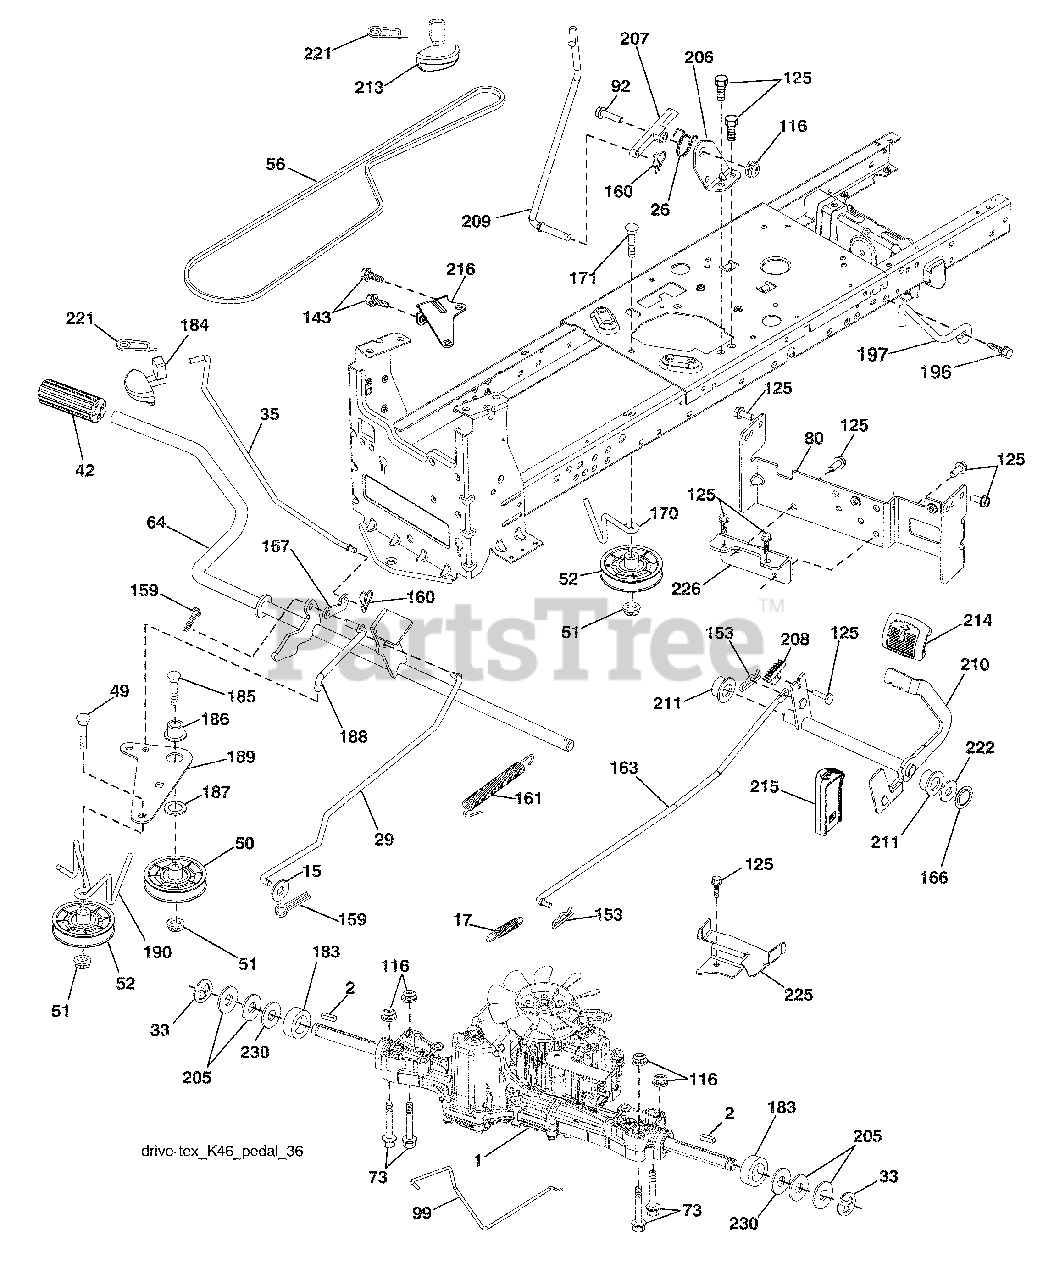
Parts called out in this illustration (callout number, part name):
1	Transaxle, TUFFTORQ K46 BT
15	Washer 13/32 x 13/16 x 16 Ga.
17	Spring, Brake
26	Spring Return Cruise
29	Rod, Brake
35	Rod, Brake, Park
42	Cover, Foot Pedal
50	Pulley Idler Flat
51	Lock Nut 3/8-16
52	Idler V-Groove 910" Offset
56	V-Belt, Drive
64	Shaft Asm. Pedal Brake Control
73	Bolt Hex Flghd 5/16-18 Gr. 5
80	Bracket Strap Torque
92	Bolt Fin Hex 5/16-18 unc x 1.25
99	Rod Asm Bypass
116	Nut Lock Hex Flange 5/16-18
125	Screw 5/16-18 x 3/4
143	Screw 5/16-18 x 1/2
153	Retainer Spring
159	Pin Cotter 1/8 x 3/4
160	Retainer Clip
161	Spring, Return, Clutch
163	Rod Pedal Control
166	Nut Push
167	Latch Brake Parking
170	Keeper Belt Centerspan
171	Bolt RDHD SQNK 3/8-16 unc x 2
183	Spacer Split
184	Handle Parking Brake
185	Bolt Rdhd Sqnk 3/8-16 x 2-3/4 Gr. 5
186	Spacer Retainer
187	Washer
188	Link Clutch Ground Drive
189	Bellcrank Ground Drive
190	Keeper Bellcrank Ground Drive
196	Screw 3/8-16 x 1
197	Bracket Clutch Anti-Rotation
206	Bracket Mount Latch Cruise
207	Latch Control Cruise
208	Gear Sector Control Cruise
209	Rod Control Cruise
210	Rocker Asm. Pedal Control
211	Bearing Nylon
213	Knob Control Cruise
214	Pedal Forward
215	Pedal Reverse
216	Bracket Pulley Idler
221	Retainer Spring Clip Handle
222	Washer 21/32 x 1-1/4 x 10 Ga.
225	Keeper Belt Trans.
226	Bracket Mount Torque
230	Washer Hardened
